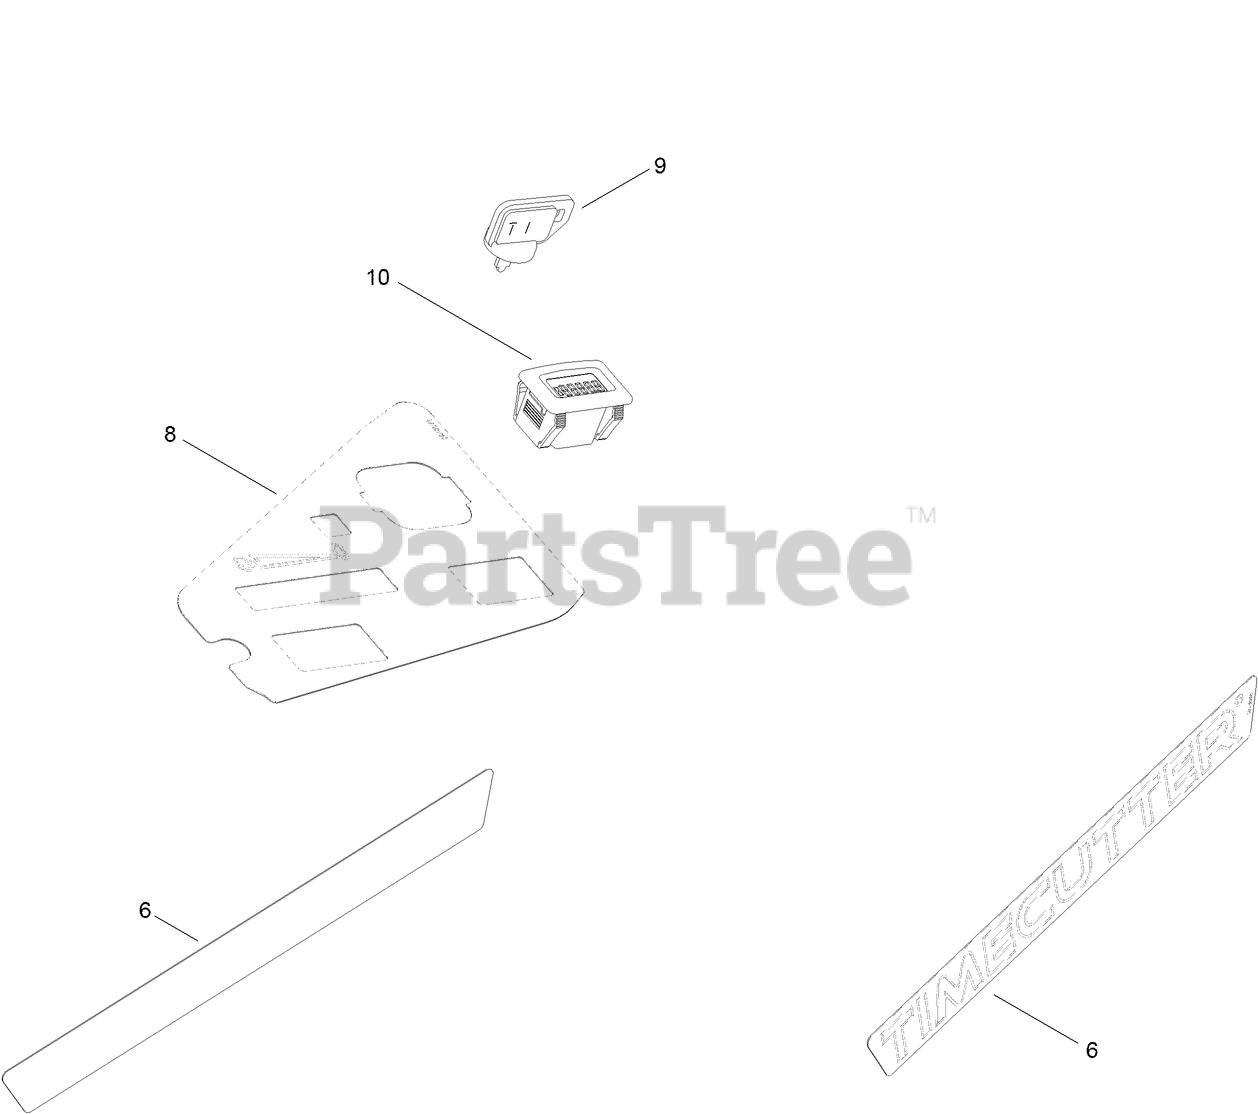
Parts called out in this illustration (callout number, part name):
6	DECAL - TIMECUTTER
8	DECAL - CONTROL PANEL
9	KEY-IGNITION
10	HOUR METER
